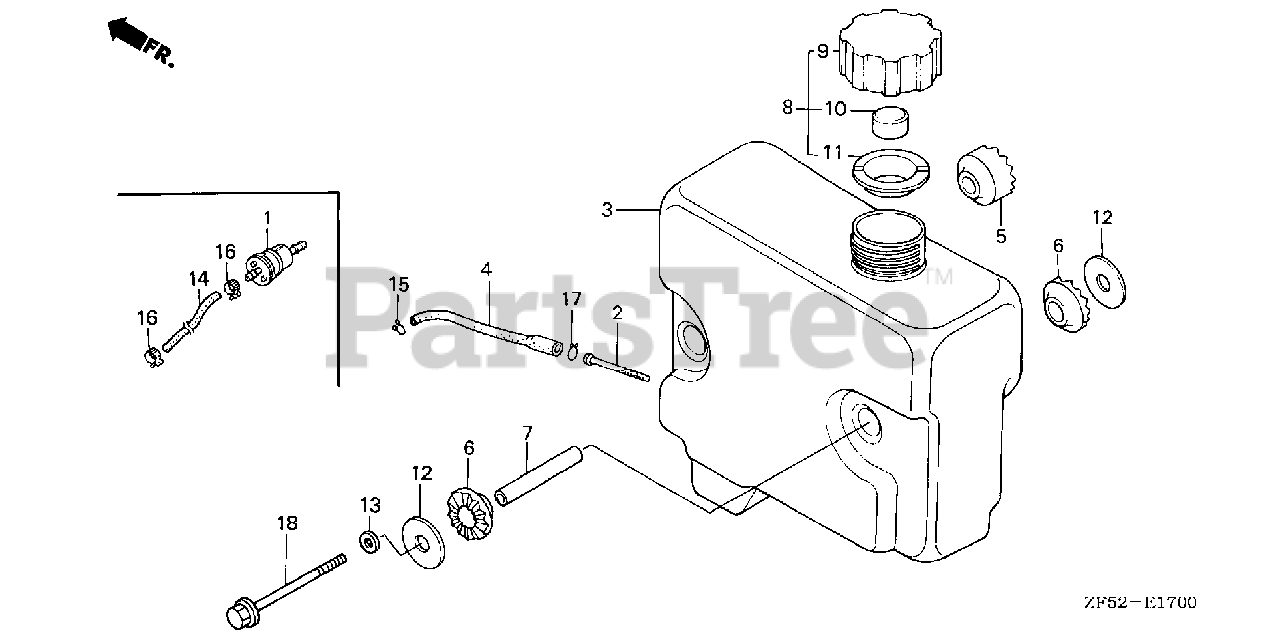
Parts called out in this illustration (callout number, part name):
2	FILTER, FUEL
3	TANK, FUEL
4	TUBE, FUEL
5	RUBBER B, TANK MOUNTING
6	RUBBER B, TANK MOUNTING
7	COLLAR, TANK SETTING
8	CAP ASSY., FUEL TANK
9	BODY, FUEL CAP
10	SPONGE, FUEL CAP BREATHER
11	GASKET, FUEL CAP
12	WASHER, TANK MOUNTING
13	WASHER, PLAIN (8MM)
15	CLIP, TUBE (B8)
17	CLIP, TUBE (C11)
18	BOLT, FLANGE (8X95)
